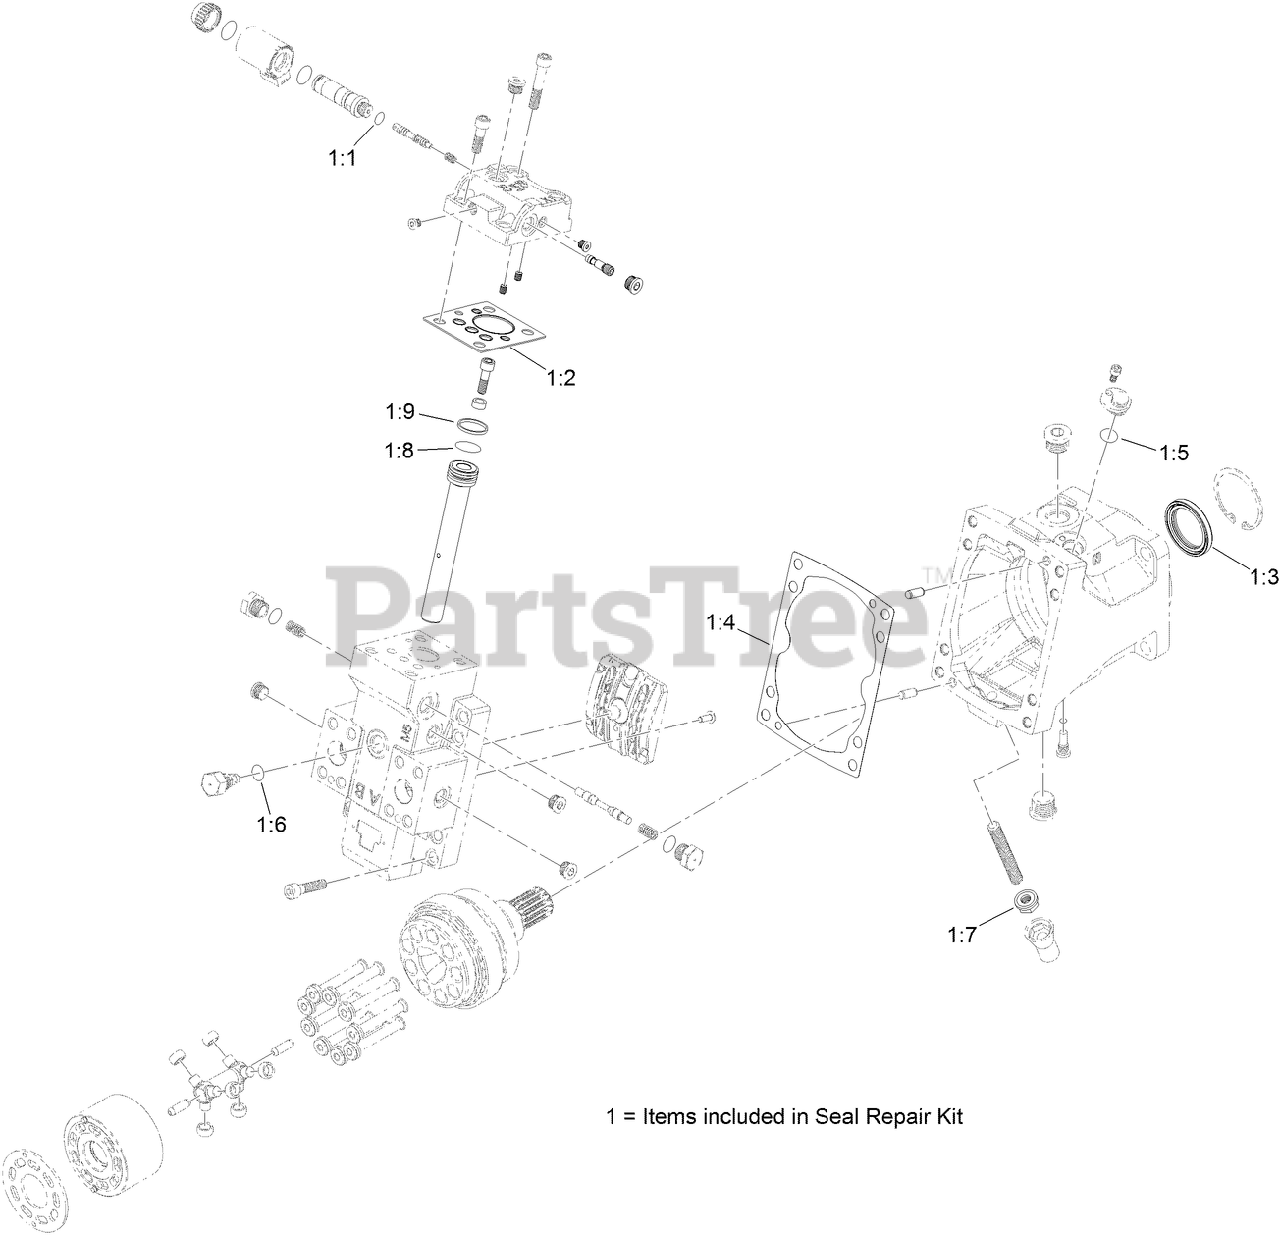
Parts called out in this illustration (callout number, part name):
1	OVERHAUL SEAL KIT
1:1	O-RING
1:2	SEAL-CONTROL
1:3	SEAL-LIP
1:4	GASKET-CAP, END
1:5	O-RING
1:6	O-RING
1:8	O-RING
1:9	RING-PISTON
